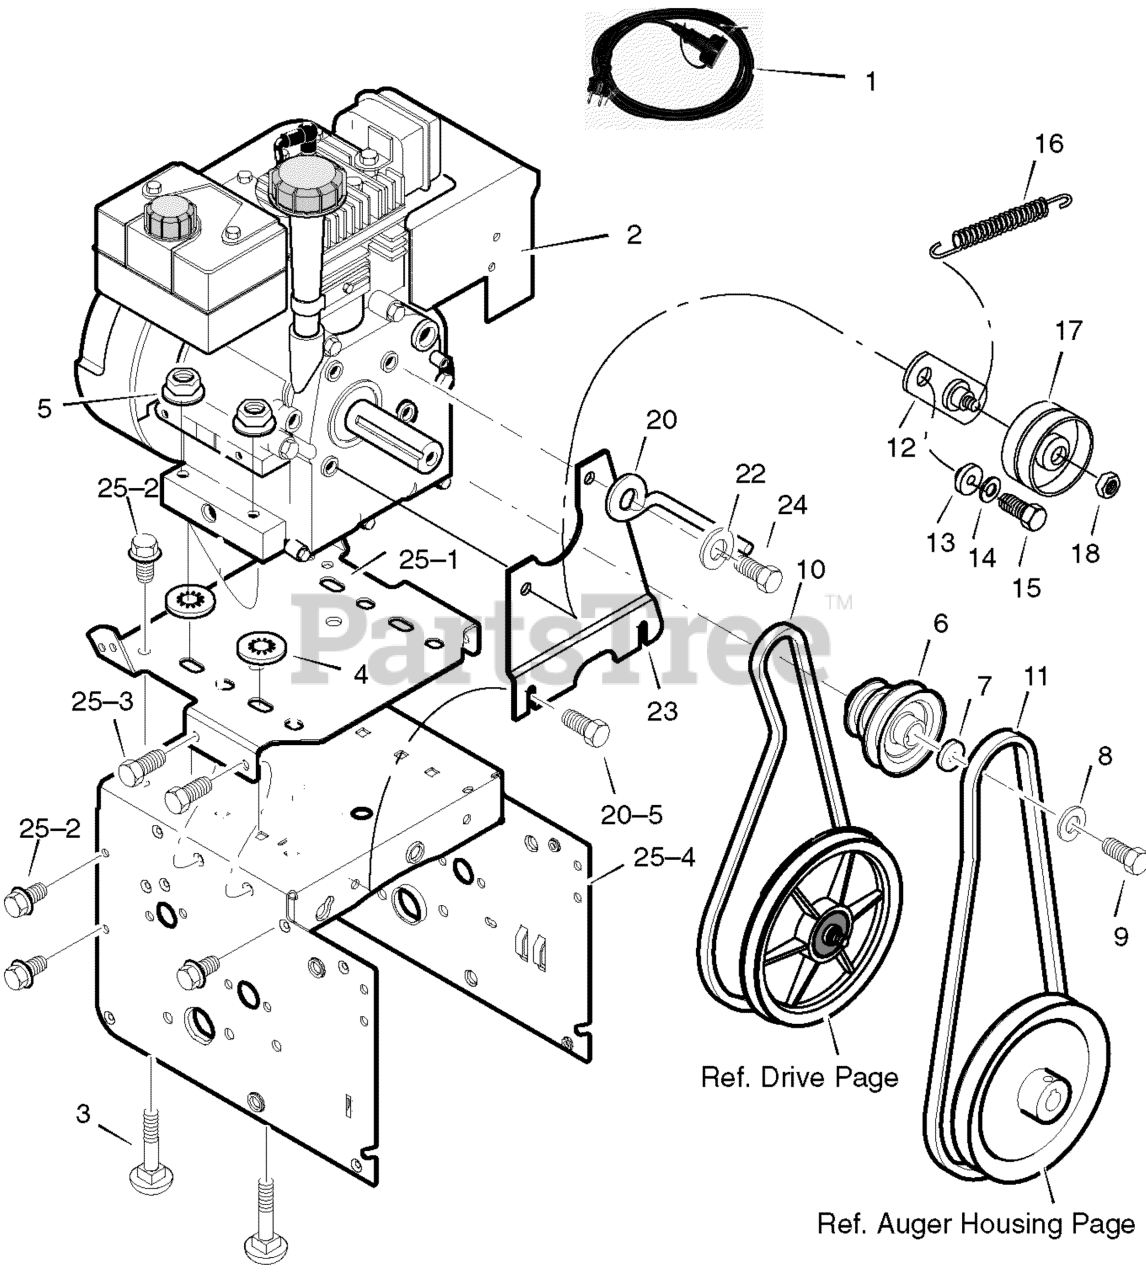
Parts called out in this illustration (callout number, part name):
1	CORD, STARTER
3	BOLT, CARRIAGE
4	RETAINER, PUSH
6	PULLEY, ENGINE
7	WASHER
8	WASHER .38ID
9	SCREW, 3/8-24 x 1.00
10	BELT, V 3L 33.13LG
11	BELT, V 4L 38.1MF16" 5-10
12	BRACKET ASSEMBLY, IDLER
13	BUSHING, IDLER BRACKET
14	WASHER, SPLIT
15	SCREW 5/16-24 X 1.00
16	SPRING, IDLER TRACTION DRIVE
17	PULLEY, IDLER
18	NUT, JAM 3/8-16
20	GUIDE, BELT
22	WASHER, SPTLK .31X.58X.08
23	PLATE, ANTI VIBRATION
24	SCREW, 5/16-24X 1.00
25	FRAME ASSEMBLY
25-1	PLATE, ENGINE MOUNT
25-2	SCREW, TAP 1/4-20 X .63
25-3	SCREW, TAP 5/16-18 X .50
25-4	FRAME, MOTOR BOX
25-5	SCREW
